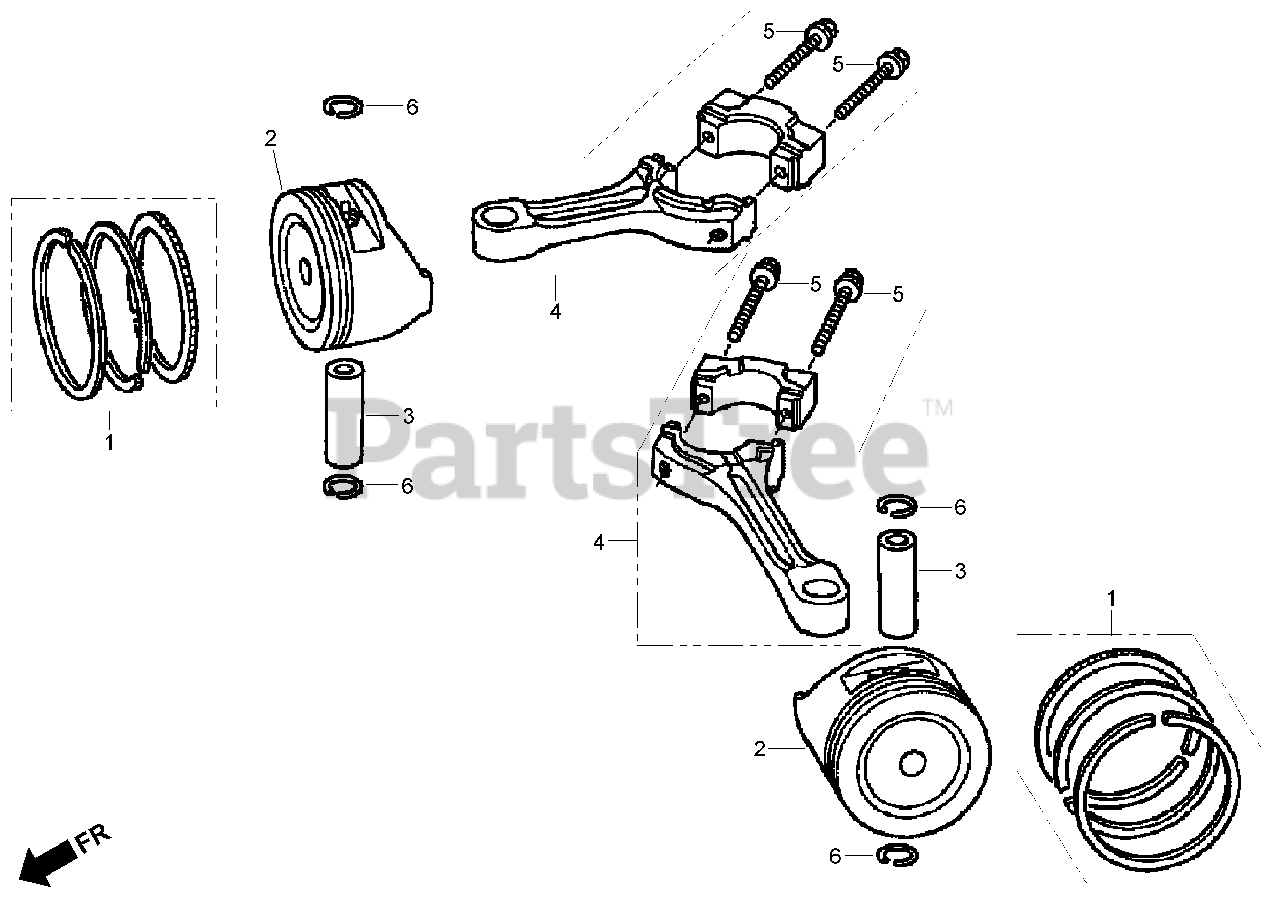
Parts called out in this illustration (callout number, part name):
1	PISTON RING SET (STD) (NIPPON)
1	PISTON RING SET
2	PISTON (STD)
3	PIN-PISTON
4	CONNECTING ROD ASM
5	BOLT-ROD, CONNECTING (6X37)
6	CLIP-PIN, PISTON (18 mm)
